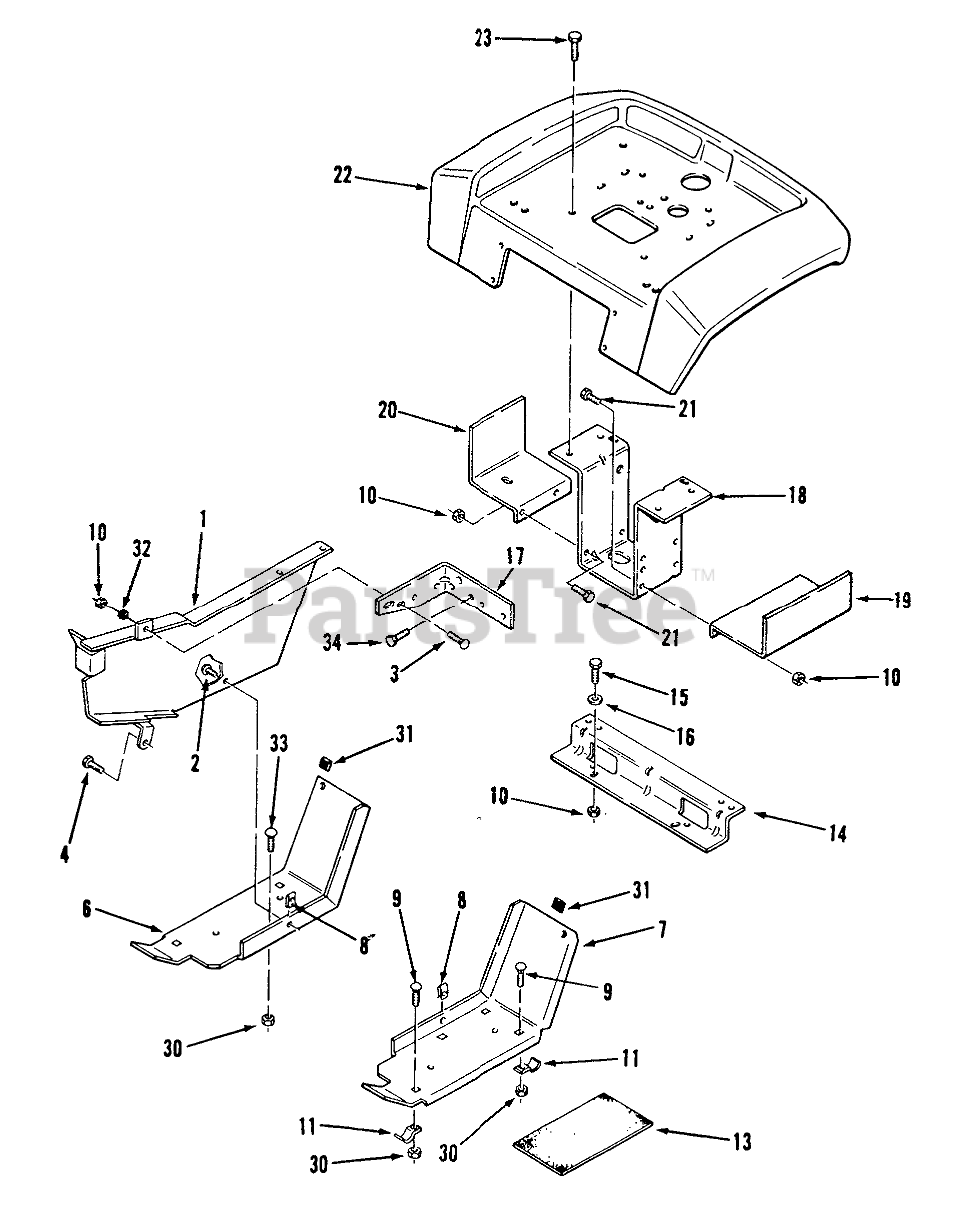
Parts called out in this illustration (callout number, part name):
1	Belt Guard
2	Screw
3	BOLT-CARR
4	SCREW
6	Footrest-RH
7	FOOTREST LH R
9	Bolt
10	Nut
11	BRACKET
13	PAD FOOTREST
14	BRACKET-FENDER B
15	Bolt
16	WASHER 5/16 SAE
17	BRACKET-BELTB
18	Bracket-Fender Support
19	Fuel Tank Support LH
20	Support-FueITank RH
21	Bolt
22	Fender
23	SCREW
24	WASHER 5/16 SAE
30	Nut
31	BUMPER
32	NUT-PUSH
33	Bolt-Carriage
34	Bolt
